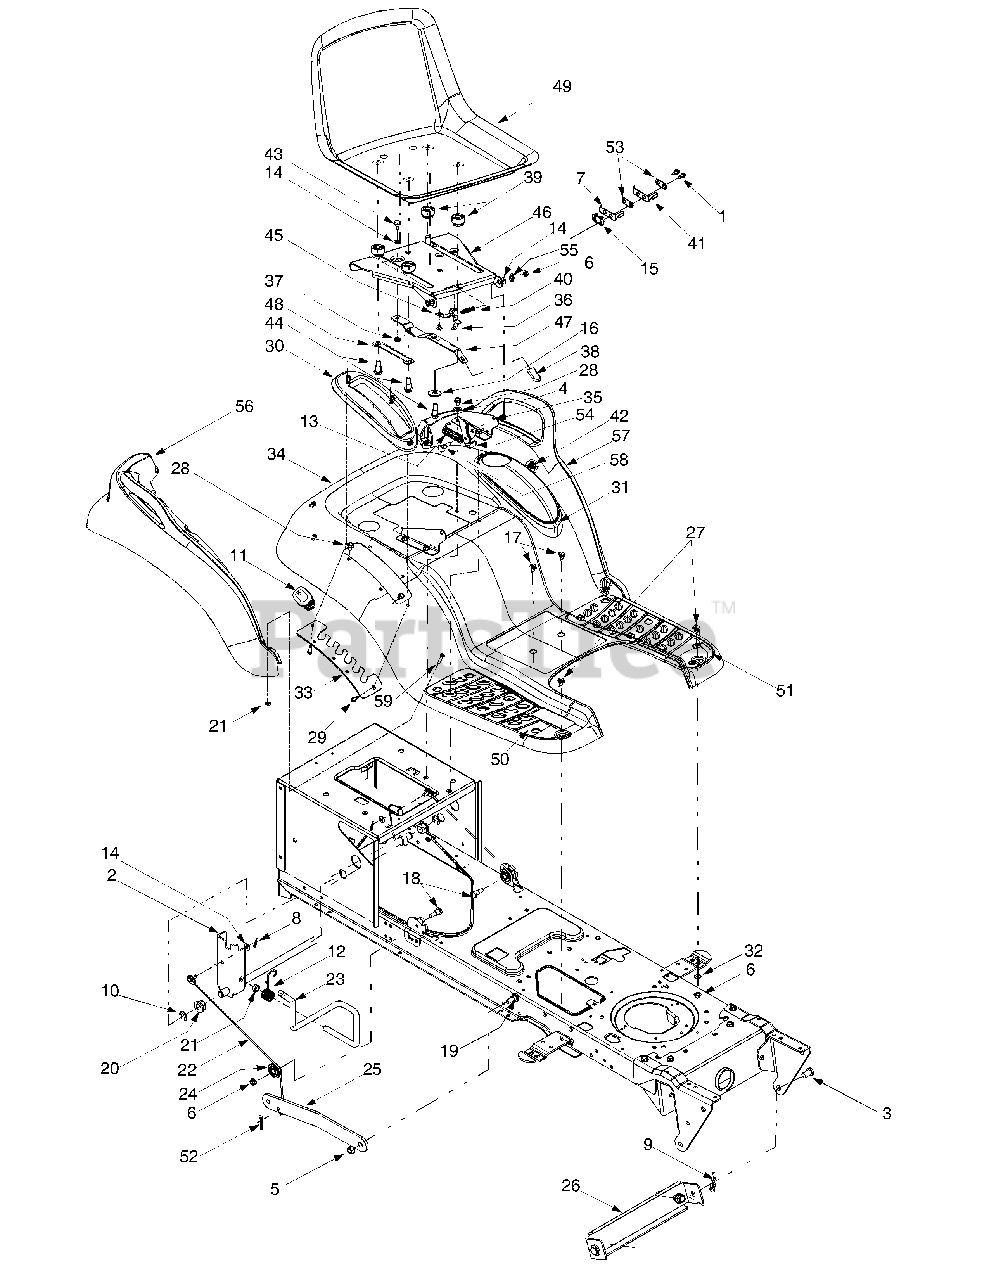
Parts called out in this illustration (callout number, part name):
1	Screw, #8-18 x.500
2	Lift Shaft Assembly Service Kit
3	Clevis Pin,.5 x.78
4	Lock Washer, 5/16
5	Flange Lock Nut, 3/8-16
6	Flange Lock Nut, 5/16-18
7	Inner Seat Spring Switch
8	Hairpin Clip
12	Torsion Spring
13	Extension Spring,.84 x 4.6
14	Flat Washer, 5/16
15	Insulator Boss Plate
16	Flat Washer,.31 x 1.062 x.134
17	Screw, 1/4-20 x.500
18	Hex Cap Screw, 5/16-18 x.62
19	Shoulder Screw, 3/8-16
20	Hex Flange Bearing
21	Sems Nut 1/4-20
22	Lift Cable, 16.16
24	Roller Pulley
27	Carriage Bolt, 5/16-18 x.750
28	Self-tapping Screw, 5/16-18 x.625
29	Self-tapping Screw, 1/4-15 x.75
30	Lift Lever Cover
31	Cover w/ Cup Holder
32	Flat Washer,.349 x 1.0 x.063
36	Screw, #10-16 x.375
37	Flange Lock Nut, 1/4-20
38	Seat Adjuster Grip
40	Compression Spring,.41 x 1.5
41	Outer Seat Spring Switch
42	Carriage Screw 1/4-20 x 1.00
43	Shoulder Screw,.340 x.285,1/4-20
44	Shoulder Screw,.50 x.50, 3/8-16
48	Seat Adjustment Selector
49	High Back Seat, Black
53	Insulator Plate
54	Seat Lift Bracket
56	RH Fender Flare
57	LH Fender Flare
58	Shoulder Screw,.437 x.286
